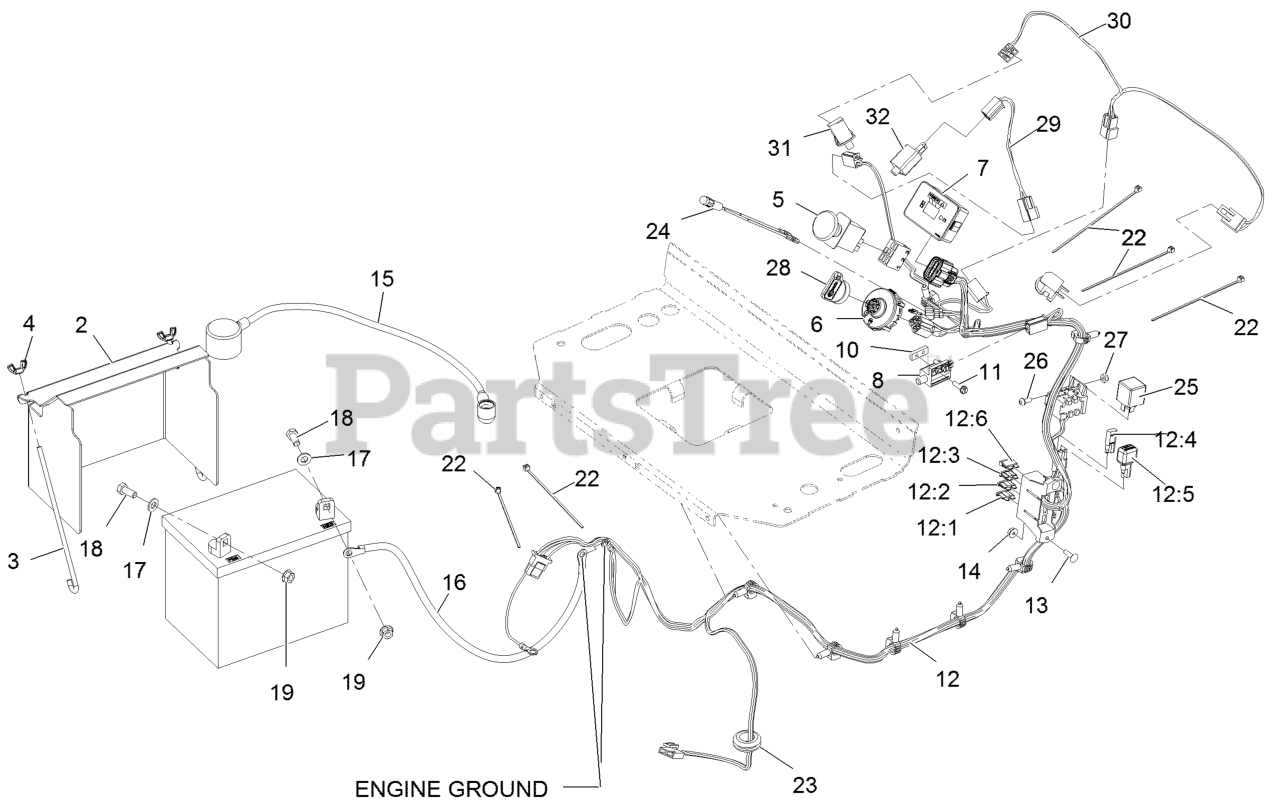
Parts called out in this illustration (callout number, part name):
2	COVER-BATTERY
3	BOLT-HOLDDOWN
4	WINGNUT
5	SWITCH-PTO, ON-ON
7	MODULE-HOUR METER
8	SWITCH-CLOSED, NORMALLY
10	PLATE-TAPPED
11	SCREW-HWH
12	HARNESS-WIRE, EFI
12:1	FUSE-BLADE, 30 AMP
12:2	FUSE-BLADE, 25 AMP
12:3	FUSE-BLADE, 10 AMP
12:6	FUSE-BLADE, 15 AMP
13	SCREW-CARR
15	CABLE-BATTERY, POSITIVE
16	CABLE-BATTERY, BLACK
17	WASHER-PLAIN
18	SCREW-HH
19	NUT-HHF, SMOOTH
22	TIE-CABLE
23	GROMMET
24	INDICATOR-LED, RED
26	SCREW-PPH
27	NUT-LOCK, NI
28	KEY-IGNITION
29	HARNESS-NEUTRAL
30	HARNESS-OPC
31	SWITCH-BAIL
32	SWITCH-OPEN, NORMALLY
